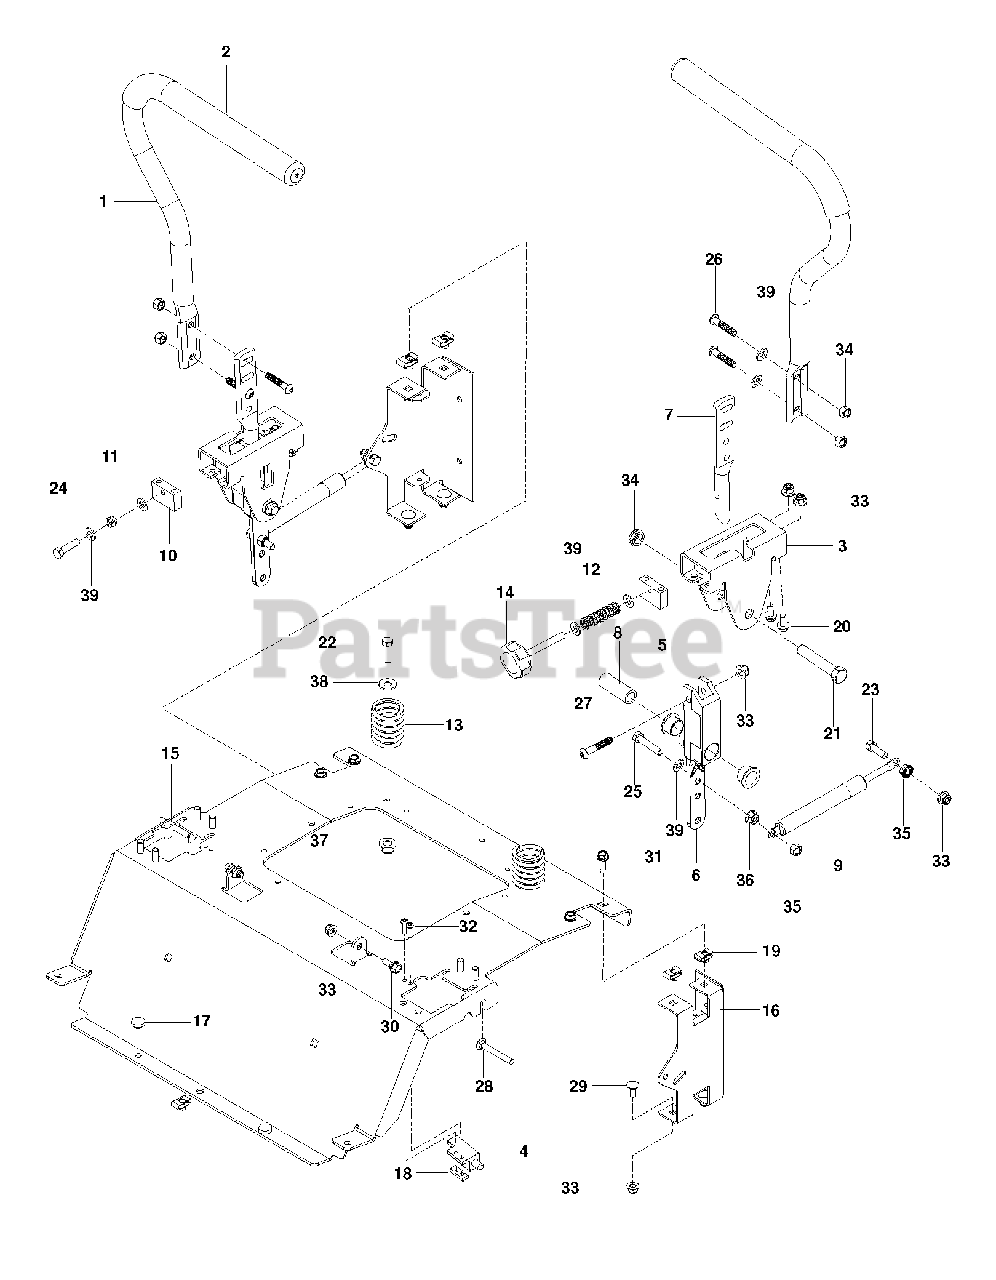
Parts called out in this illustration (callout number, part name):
1	LEVER.STEERING.ASM.(W/GRIP)
2	GRIP, DRIVE LEVER
3	BRACKET, CONTROL
4	SWITCH INTERLOCKT
5	BEARING, FLANGE
6	LEVER CONTROL PIVOT
7	LEVER.HANDLE MOUNT
8	SPACER, PIVOT CONTROL
10	BLOCK.TRACKING
12	SPRING COMPRESSION 2.0
13	SPRING, SEAT
15	SUPPORT SEAT ORANGE
16	SUPPORT, REAR SEAT, BLACK
17	GROMMET, BUMPER
18	TAPPED PLATE
19	U-CLIP 5/16-18 NUT RETAINER
20	HHFS 5/16-18 X 3/4
21	HCS 1/2-13 X 2-3/4 GD 5 ZD
22	BOLT
23	BOLT.FIN.HEX.5/16-18UNC X 1.00
24	HEX BOLT
26	SCREW BUTTONHEAD 5/16-18X1-1/2
27	SCREW 5/16-18 X 1 3/4 BTN-HD
28	RHSNB 5/16-18 X 2-1/2 GR5 ZD
29	BOLT 5/16-18 X3/4 ZN/YEL GR 5
30	BOLT, SHOULDER
31	SCREW
32	SCR #10-24 X .75 SKT HD BLK
33	5/16-18 NYLOC FLANGE NUT
34	NUT 1/2-13 HEX JM NYL
35	NUT.71038.31-18.HEX.NYLOCK
36	NUT 5/16C WHIZ
37	NUT 3/8-16 HEX FLG NYLOC ZD
38	WASHER 3/8 FLAT
39	WASHER
